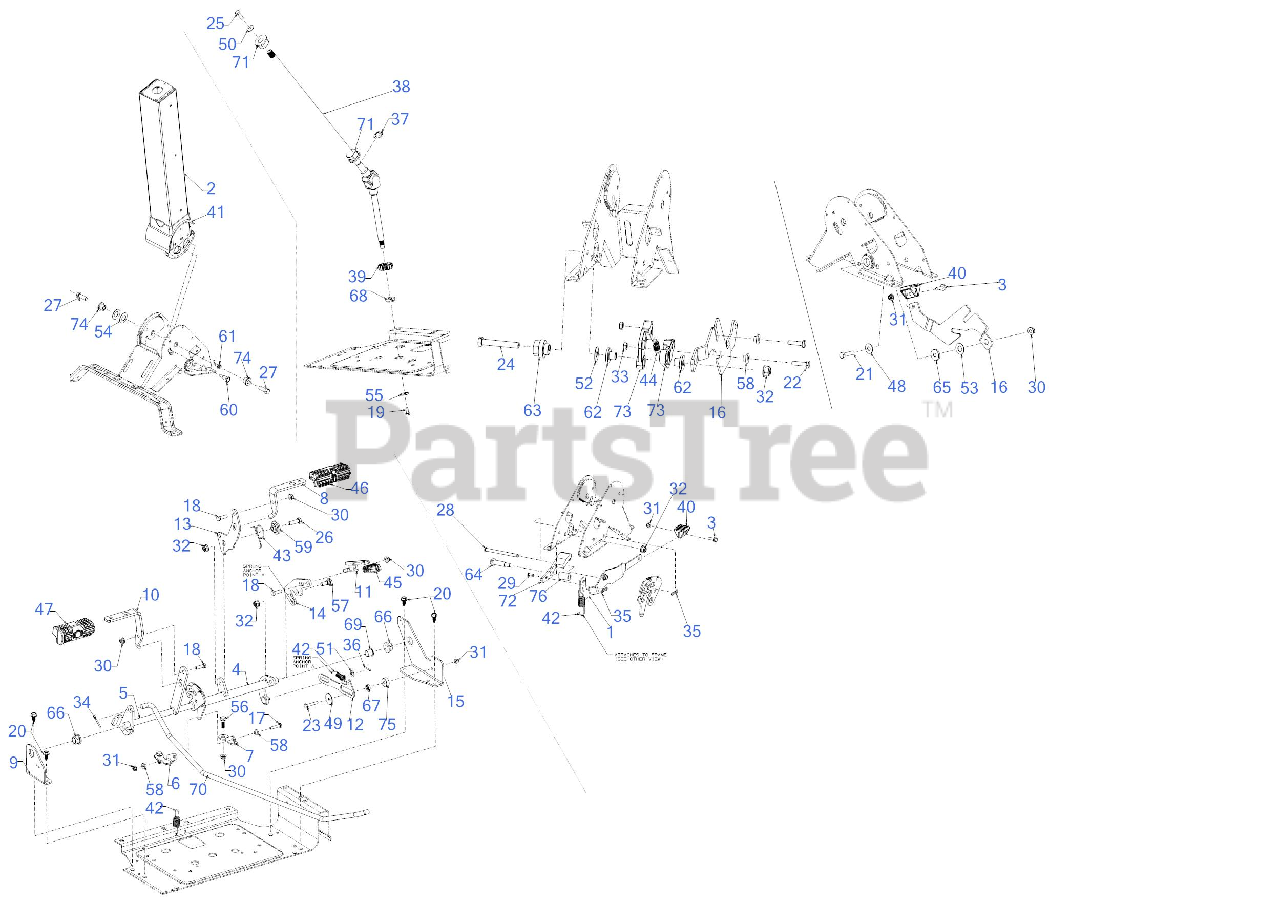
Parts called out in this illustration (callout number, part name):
3	HEX SCREW 1/4-20X.
4	DRIVE PEDAL SHAFT ASSEMBLY
5	BRAKE SHAFT ASSEMBLY
12	NEUTRAL RETURN LINK
13	FORWARD PEDAL BRACKET
14	REVERSE PEDAL PIVOT PLATE
17	HEX SCREW 1/4-20 x 1.25
18	SCREW 5/16-18 x 1.0 GR5
19	SCREW 1/4-20 x .62 SPEC GR5
20	SCREW 5/16-18 x .750
21	SCREW 5/16-18 x 1.25 GR5
22	SCREW 1/4-20 X1.00 GR5
23	SCREW 1/4-20 x 1.50 GR.5
24	HEX SCREW-3/8-16X2.5 GR5
25	SCREW 5/16-24 x .875 GR5
26	SCREW 3/8-16 x 1.25 GR5
27	SCREW 3/8-16X1.0 GR5
28	CLEVIS PIN 5/16 x 4.135
29	CLEVIS PIN .224 x .625
30	FLANGE LOCK NUT 5/16-18
31	FLANGE LOCK NUT
33	HEX NUT 1/4-20
34	COTTER PIN-5/32 DIA
35	BOW TIE COTTER PIN 1/4-5/16
36	COTTER PIN
37	E-RING
38	STEERING SHAFT ASSEMBLY
39	STEERING GEAR 14T
40	CRUISE TILT KNOB
41	STEERING COLUMN COVER
42	EXTENSION SPRING
43	TORSION SPRING
44	EXTENSION SPRING .40 ODx1.50 LG
45	REVERSE PEDAL PAD
46	FORWARD PEDAL PAD
47	BRAKE PEDAL PAD
48	FLAT WASHER
49	FLAT WASHER
50	BELL WASHER .337 X.867 x .057
51	WASHER THRUST .375X.70X.030
52	FLAT WASHER
53	FLAT WASHER .508X1.000X.040
54	BELLEVILLE WASHER 1.24X.642X.049
55	FLAT WASHER
56	SHOULDER SCREW .437
57	SHOULDER SCREW
58	SHOULDER SPACER
59	SHOULDER SPACER 1.50X.38X.38
60	SHOULDER BOLT .395 DIA x .56 LG
61	SHOULDER SCREW M6-1 .368 X.115
62	SHOULDER SPACER (.500x1.00x.440)
63	TILT ADJUSTMENT BUSHING
64	SHOULDER SCREW .496X1.44 3/8-16
65	SHOULDER SPACER
66	FLANGE BEARING
67	BALL BEARING .25 x .625 SPCL
68	HEX FLANGE BEARING 7/16
69	NYLINER BEARING
70	FRONT BRAKE ROD
71	FLANGE BEARING
72	CRUISE LATCH
73	TILT STEERING PAWL
74	SHOULDER SPACER .381X.626X.414
75	SPACER .267X1.00X.36
76	SPACER 0.510 x 0.775 x 1.190
